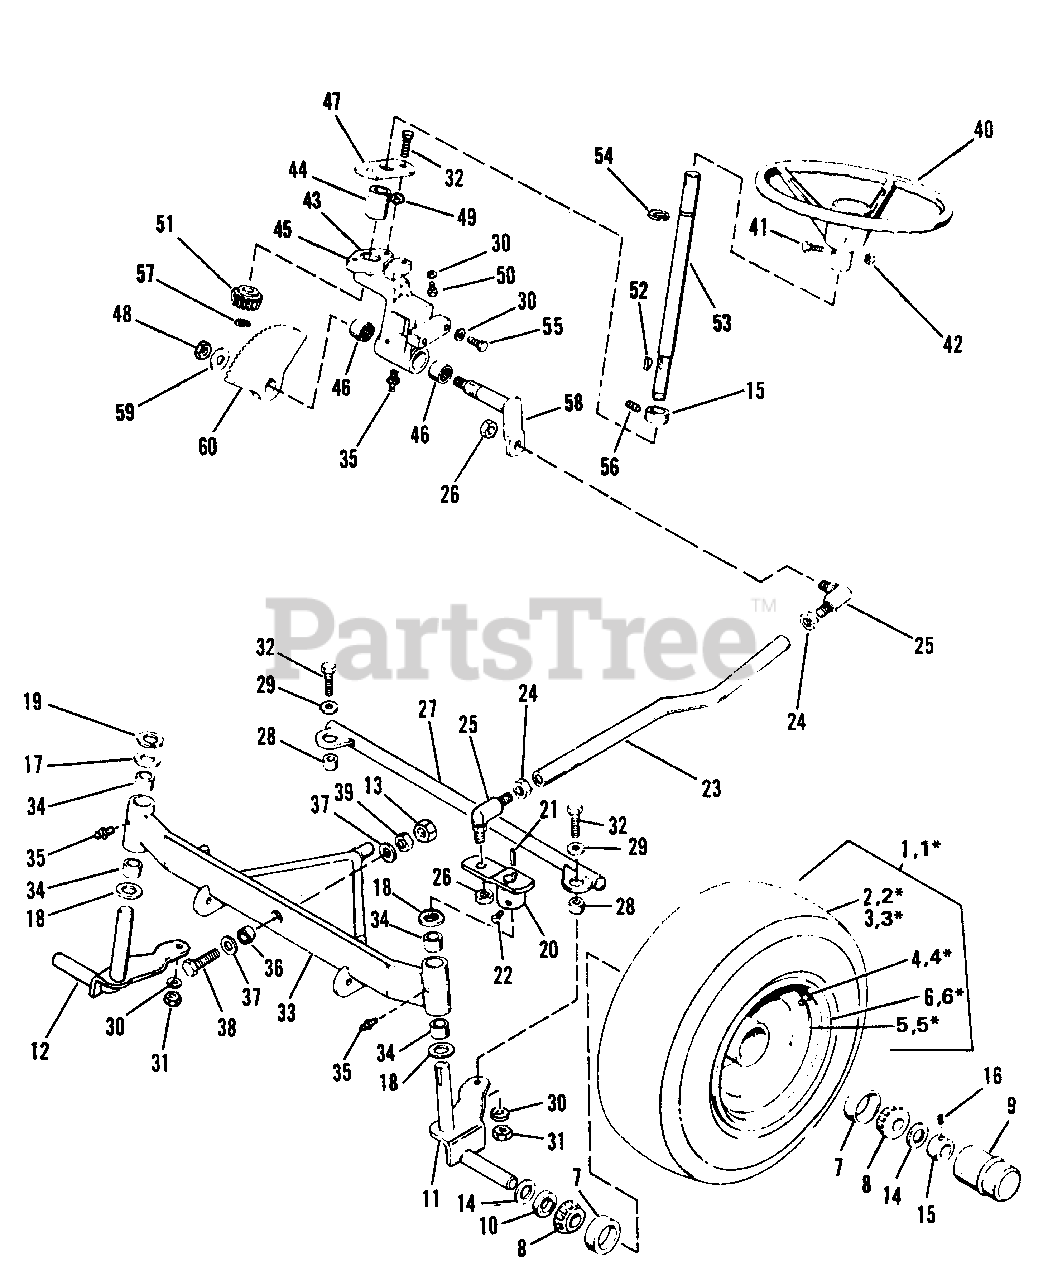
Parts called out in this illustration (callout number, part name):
1	WHEEL & TIRE ASSEMBLY
2	TIRE
3	TUBE
4	STEM, Valve & Cap
5	WHEEL, Sub Assy.
6	WHEEL, Front
7	CUP, Bearing
8	CONE, Bearing
9	CAP, Hub
11	SPINDLE ASSEMBLY, L.H.
12	SPINDLE ASSEMBLY, R.H.
13	NUT, Hex Jam, 1/2-13
15	COLLAR, Set
16	SETSCREW, 5/16-18 x 5/16" lg.
19	RlNG, Retaining
20	ARM ASSEMBLY, Steering L.H.
22	SETSCREW, 5/16-18 x 1/2" lg.
24	NUT, Jam, 1/2-20
25	JOINT, Ball
26	LOCKNUT, Hex, Jam, 1/2"-20
27	LINK ASSY., Drag
29	WASHER, Plain, 3/8"
30	LOCK WASHER, 3/8"
31	NUT, full hex, 3/8-16
32	CAPSCREW, Hex, 3/8-16 x 1-1/4" lg.
33	AXLE ASSY., Front
35	FITTING, Grease
37	WASHER, Plain, 1/2"
38	CAPSCREW, Hex
39	NUT, Toplo, 1/2"-13
40	WHEEL, Steering
41	CAPSCREW, Hex, 5/16-18 x 1-1/4" lg.
42	LOCKNUT, Flange, 5/16-18
43	CASTING, Steering
45	CASTING, w/ Bearings
46	BEARING, Needle
47	PLATE, Steering
48	LOCKNUT, Full Hex, 7/16-14
49	LOCKNUT, Hex Jam, 3/8-16
50	CAPSCREW, Hex, 3/8-16, x 3/4" lg.
53	SHAFT, Steering
54	RING, Retaining
55	CAPSCREW, Hex, 3/8"-16 x 7/8" lg.
56	SETSCREW, 5/16-18
57	RING,"E"
58	ARM ASSY., Steering
59	WASHER, Plain 7/16"
